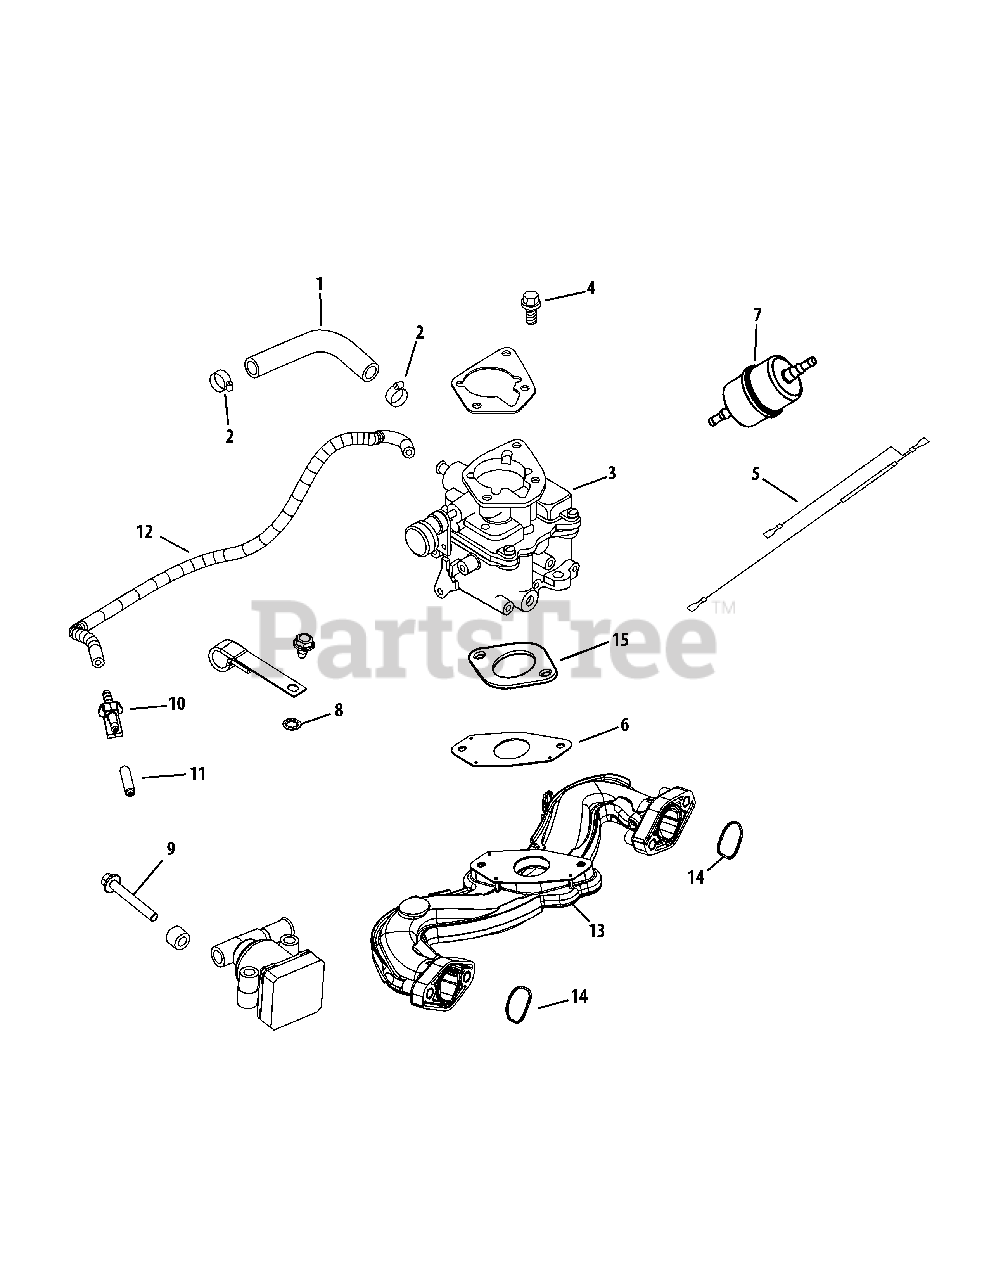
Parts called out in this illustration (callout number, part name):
1	Low Permeation Fuel Hose, 24"
3	Carburetor Kit w/ Gaskets
4	Flange Screw, M6 x 1.0 x 25
5	Internal Tooth Lock Washer, 1/4
6	Carburetor Gasket
7	Fuel Filter
9	Flange Screw, M6 x 1.0 x 40
10	Evaporative Connector
12	Evaporative Hose, 20"
13	Intake Manifold Kit
14	Intake Port O-Ring
15	Carburetor Gasket
